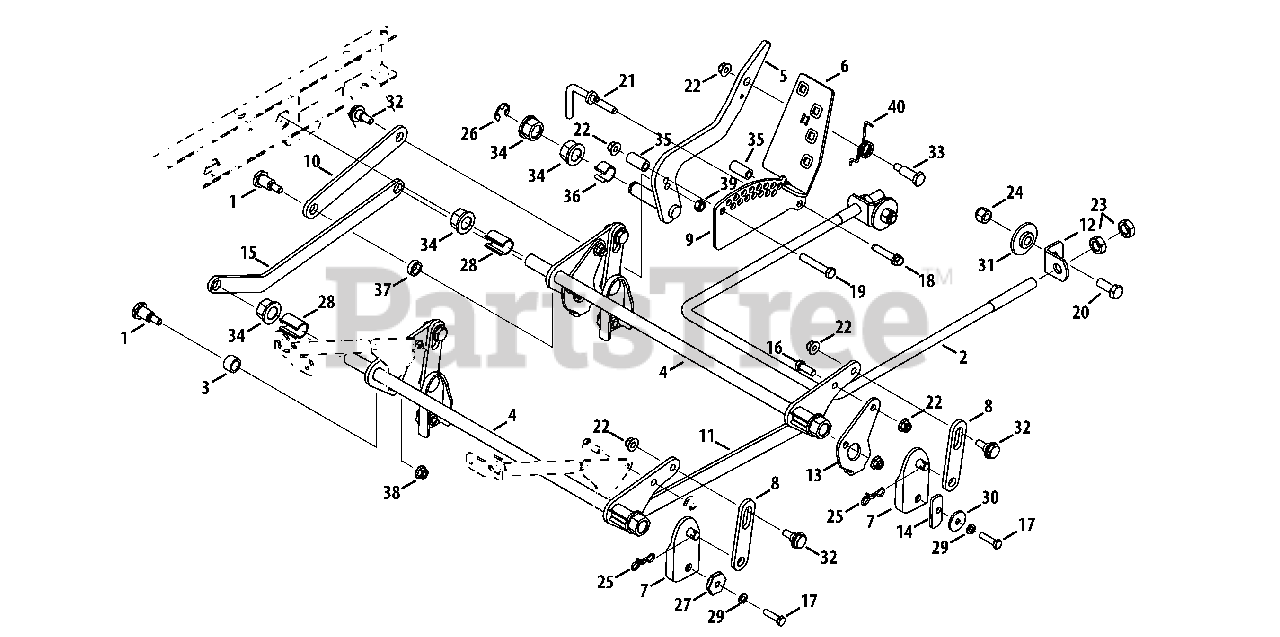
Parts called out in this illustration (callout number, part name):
1	Shoulder Screw, .625 x .830
3	Spacer, .632 x .877 x .548
4	Rock Shaft Assembly
5	Foot Pivot Assembly
10	Pedal Link Plate
11	Mid Link Plate
12	Front Hanger Rod Bracket Mount
13	Deck Up Stop Bracket
14	Deck Lift Square Spacer
15	Mid-Angled Link Plate
16	Hex Screw, 3/8-16 x 1.00
17	Hex Screw, 5/16-18 x 1.25
18	Hex Washer Screw, 3/8-16 x 1.875
19	Hex Screw, 3/8-16 x 2.25
20	Hex Screw, 1/2-13 x 1.25
22	Flange Lock Nut, 3/8-16
23	Jam Nut, 1/2-13
24	Hex Lock Nut, 1/2-13
25	Cotter Pin
26	E-Type Ring, .750
27	Adjustable Deck Gear
28	Spacer, .791 x .950 x 1.35
29	Lock Washer, 5/16
30	Flat Washer, .330 x 1.25 x .120
31	Shoulder Spacer, .9790 x .2025
32	Shoulder Spacer, 3/8-16 x .562 x .360
33	Shoulder Screw, .500 x 1.25
34	Hex Flange Bearing, .752
35	Spacer, .375 x .625 x 1.34
36	Spacer, .79 x .95 x .73
37	Spacer, .632 x .877 x .281
38	Flange Lock Nut, 7/16-20
39	Hex Lock Nut, 3/8-16
40	Torsion Spring
